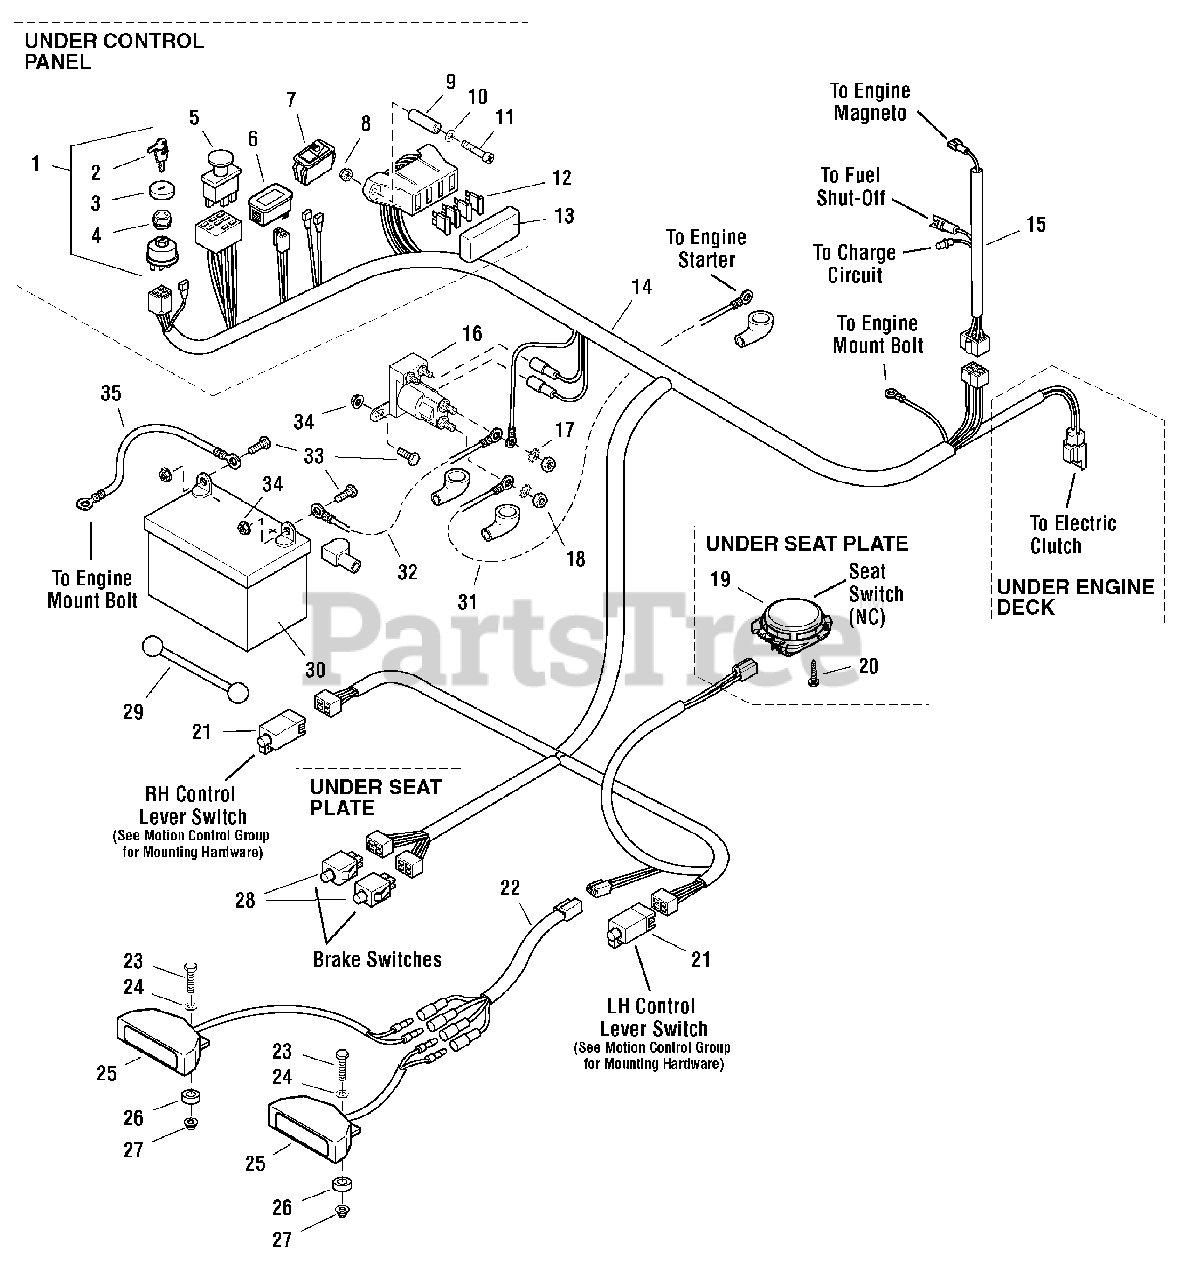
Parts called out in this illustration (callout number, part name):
1	SWITCH, Ignition, Complete (Includes Ref No. 2 - 4)
2	KEY, Ignition Molded (Set of 2)
4	PLASTIC NUT
5	SWITCH, PTO
7	HEADLIGHT SWITCH
8	NUT, #10-24 Hex Nylon Lock
9	SPACER, .20 x .38 x 1.25
10	WASHER, #10 SAE
11	SCREW, #10-24 x 2"
13	FUSE BLOCK COVER
14	HARNESS ASSEMBLY, Main
15	ENGINE HARNESS
16	SOLENOID
17	WASHER, Light Lock, 5/16
18	NUT, Hex Jam, 5/16-24
19	SWITCH, Seat, Gray, NC
20	BOLT, Hex Washer Head PLASTITE, 1/4 X 1/2
21	SWITCH, PLUNGER, N.O./N.C.
22	HEADLIGHT HARNESS
23	BOLT, 1/4-20 X 1-1/4
24	WASHER, 1/4 SAE (5025154)
25	HEADLIGHT
26	SPACER, .39 X .75 X .38
27	NUT, 1/4-20 HEX NYLOCK FLANGE (5025391)
28	SWITCH, DP NO/NC SNAP-IN
29	STRAP, BATTERY, 14 LONG, Rubber
30	BATTERY, Lawn & Garden, 12V (BCIU1, 340 CCA)
31	POSITIVE (+) BATTERY CABLE, 22"
32	POSITIVE (+) BATTERY CABLE, 22"
33	BOLT, 1/4-20 x 3/4
34	NUT, 1/4-20 Hex Serrated Flange
35	CABLE, Ground
